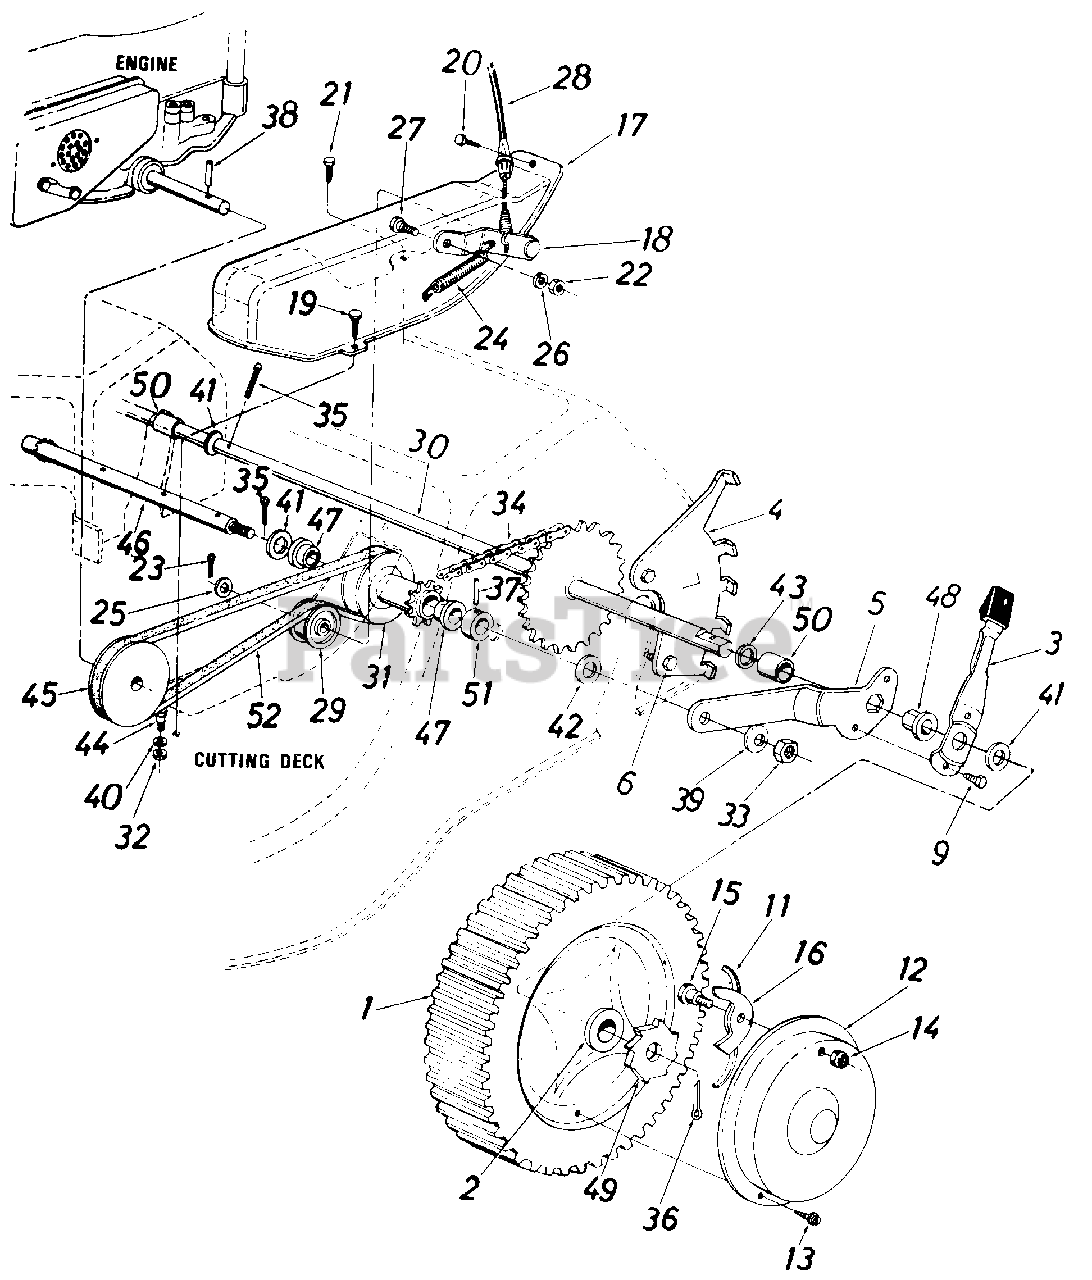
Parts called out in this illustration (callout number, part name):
1	Wheel Ass'y. Comp. 8.0 x 1 .75
2	Flange Brg.-1/2" I.D.
3	Spring Leverw/Knob
4	Index Plate-L.H.
5	Pivot Brkt.-L.H.
6	Hex Wash. Hd. Tap Scr. 1/4 x .62" Lg.
9	Hex B-Tap Scr. 1/4 x .38" Lg.
11	Nylon Spring
12	Hub Cap
13	Pan Hd. Tap Scr. #12 x .50" Lg.
14	Hex ins. L-Nut 1/4-20 Thd.
15	Shld. Bolt .342" Dia. x.268
16	Pawl
17	Belt Cover
18	Idler Bracket Ass'y.
19	Hex Wash. Hd. Self-Tap Scr. 1/4 -20 x .50" Lg.
20	Hex Drilling Scr. #10 x .50" Lg.
21	Hex TT-Tap Scr.1/4-20 x .75" Lg.
22	Hex Nut 1/4 -20 Thd.
23	Cotter Pin 118" Dia. x 1.00"
24	Extension Spring .33" O.D. x 1.12" Lg.
25	Fl-Wash. .531" I.D. x .930" O.D.
26	L-Wash. 1/4" I.D.
27	Shld. Bolt .375" Dia. x .181
28	Clutch Cable-50"
29	Flat Idler-Plastic
30	Rear Shaft Ass'y.
31	Pulley w/9 Tooth Sprocket Ass'y.
32	Hex Nut 5/16-18 Thd.*
33	Hex Jam Nut 3/8-16 Thd.
34	#48 Chain 1/2" Pitch x 31 Links
35	Cotter Pin 31/32" Dia. x 1.00" Lg.*
36	Cotter Pin 1/8" Dia. x 1.00" Lg.*
37	Spring Pin Spir. 3/16" Dia. x 1.00" Lg.
38	Spring Pin Spir. 3/16" Dia. x 1.50" Lg.
39	Bell-Wash. .400" I.D. x .88" O.D.
40	L-Wash. 5/16" I.D.
41	Fl-Wash. .531" I.D. x .930" O.D.
42	Bell-Wash. .400" I.D. x 1.13" O.D.
43	Fl-Wash. .510" I.D. x 1.0" O.D
44	Shld. Bolt .437" Dia. x .350" Lg.
45	Engine Pulley
46	Pulley Shaft-10.0" Lg.
47	Flange Brg. .506" I.D. Plastic
48	Hex Flange Brg. x .506" I.D. Plastic
49	Ratchet
50	Spacer.765" I.D. x .89" O.D. x .960" Lg.
51	Spacer. 505" I.D. x .88" O.D. x.44" Lg.
52	"V"-Belt 1/2" x 33" Lg.
